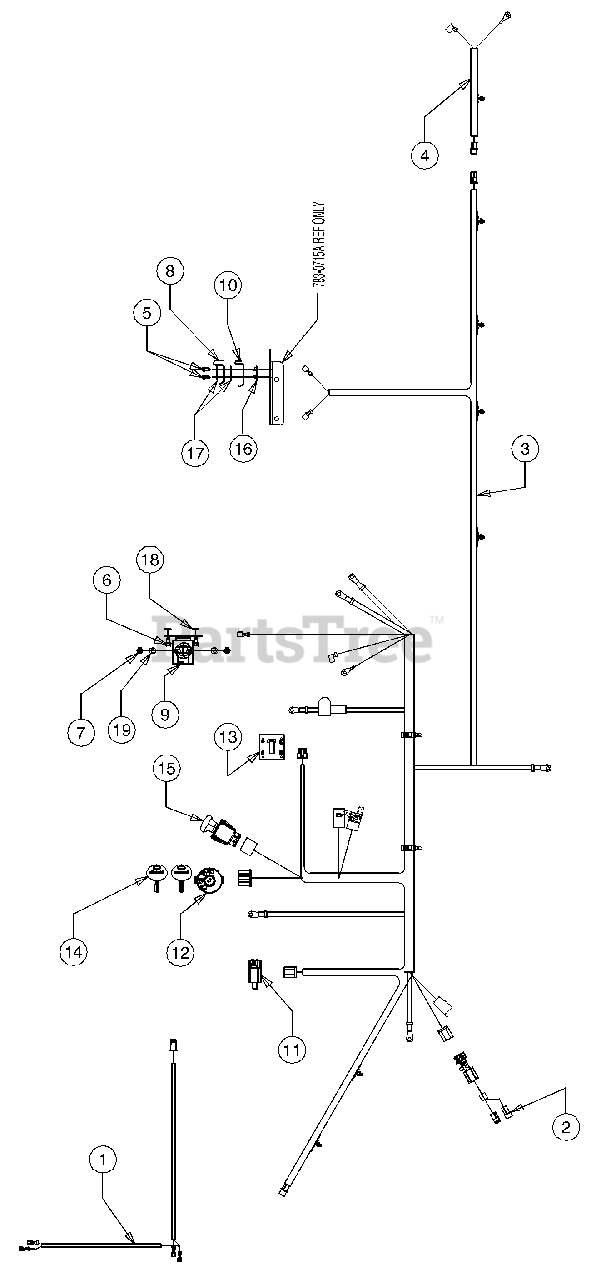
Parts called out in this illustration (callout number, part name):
1	Harness Assembly, Headlight
2	Harness Assembly, Kohler OHV Alternator
3	Harness Assembly, Kohler,
4	Harness Assembly, Safety, Reverse
5	Screw, Ab, #8-18, 0.500
6	Screw, Self-tapping, 1/4-20, 0.500
7	Nut, Hex, 1/4-20, Gr5
8	Switch, Outer Seat Spring
9	Solenoid, 12V, 100amp
10	Switch, Inner Seat Spring
11	Switch, Snap Mount
12	Switch, Key, 4-Position
13	Indicator, Monitor, Hour Meter
14	Key, Switch, Plastic
15	Switch, Electric PTO, Yellow Knob
16	Plate, Insulator Boss
17	Plate, Insulator
18	Washer, Lock, Ext 1/4
19	Washer, Lock, 1/4, Regular Duty
